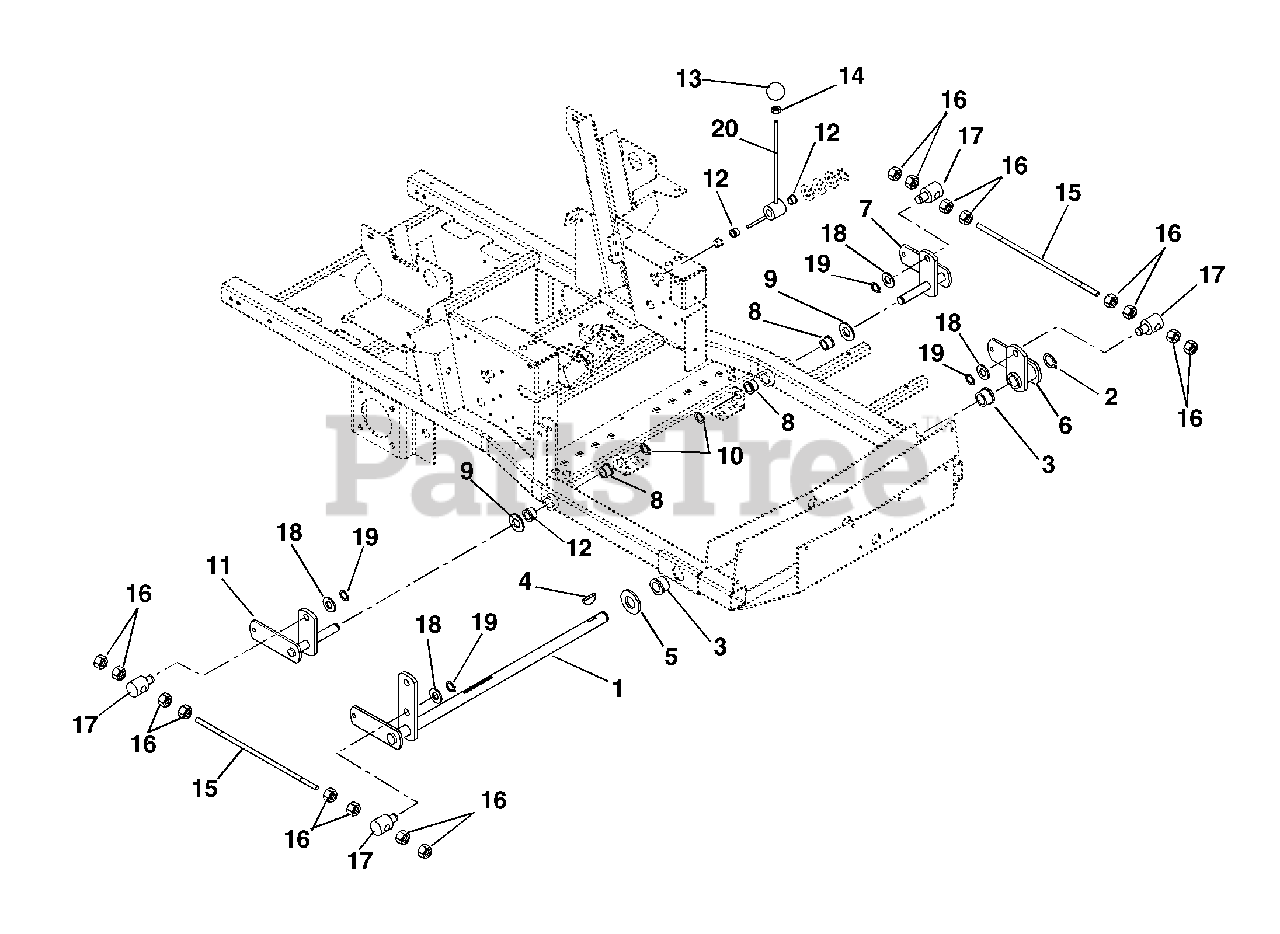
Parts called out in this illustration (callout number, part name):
1	Lift-Mower
2	Ring-Retaining-External 1.00 x .078
3	Bushing-Flange-Nylon 1.020 x 1.385 x .75 x 1.75
4	Key-Woodruff .25 x 1.00
5	Washer-Flat-Steel 1.063 x 2.00 x .134
6	Weldment, Lift Arm-Front
7	Weldment, Lift Arm-Shaft-Left Hand
8	Bushing-Flange-Nylon .762 x 1.0 x .580 x 1.48
9	Washer-Hardened-Steel .758 x 1.23 x .031
10	Ring-Retaining-External .689 x .077
11	Weldment, Lift Arm Shaft-Right Hand
12	Bushing-Flange .63 x 1.00 x .625
13	Knob-Steering Lock
14	Nut-Hex-Jam .375 -16
15	Rod-Lift Assist
16	Nut-Jam .50-13
17	Pivot-Mower Lift
18	Washer-Flat-Steel .630 x 1.005 x .062
19	Ring-Retaining-External .625 x 050
20	Lever-Deck Lift
